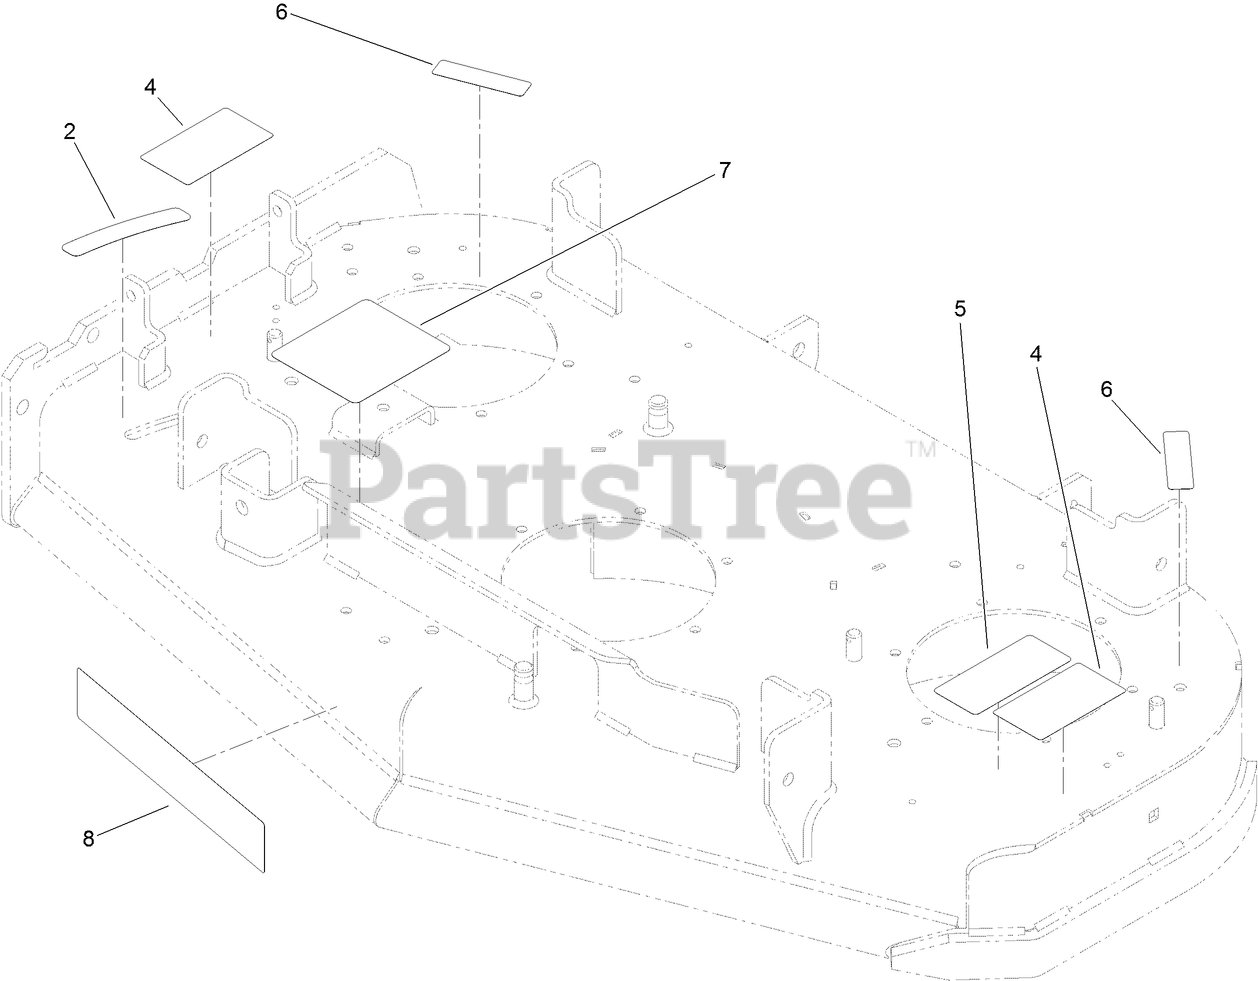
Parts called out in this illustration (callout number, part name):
2	DECAL-SETTING, BAFFLE
4	DECAL-DANGER
5	DECAL-TORQUE, BLADE BOLT
6	DECAL-DANGER
7	DECAL-ROUTING, BELT
